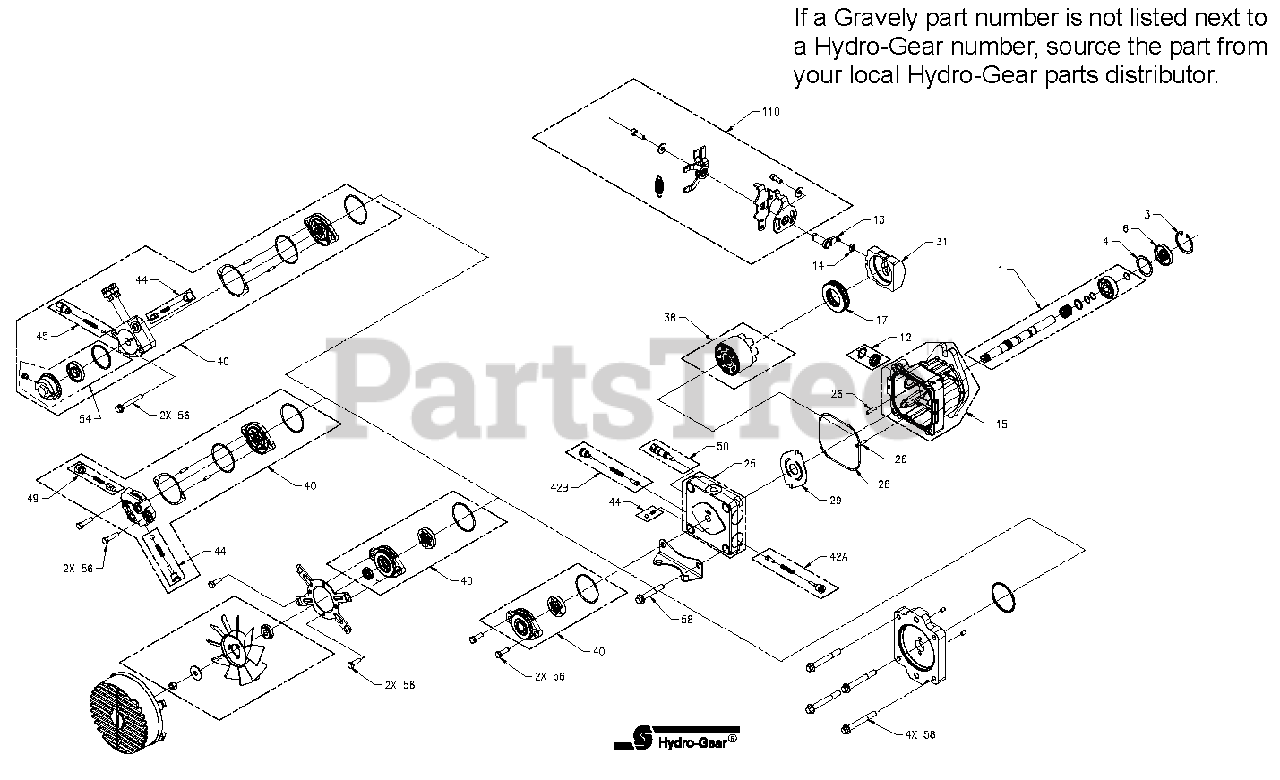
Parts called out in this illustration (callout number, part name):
1	Kit, Input Shaft
3	Ring, Retaining
4	Washer, 1.45 x 1.84 x .04
6	Lip Seal, 17 x 47 x 8
12	Kit, Trunnion Seal
13	Trunnion Arm, Taper Square
14	Slot Guide
15	Kit, Housing
17	Assembly, Thrust Ball Bearing
25	Kit, Encap
26	Pin
28	O-Ring
29	Valve Plate
31	Variable Swashplate
38	Kit, Cylinder Block
42	Kit, Shock Valve
44	Kit, Charge Relief
45	Kit, Auxilary Relief Valve
50	Kit, Bypass Valve
54	Kit, Auxilary Filter Kit
56	Screw, 5/16-18 x 1
58	Kit, HSG Bolt
